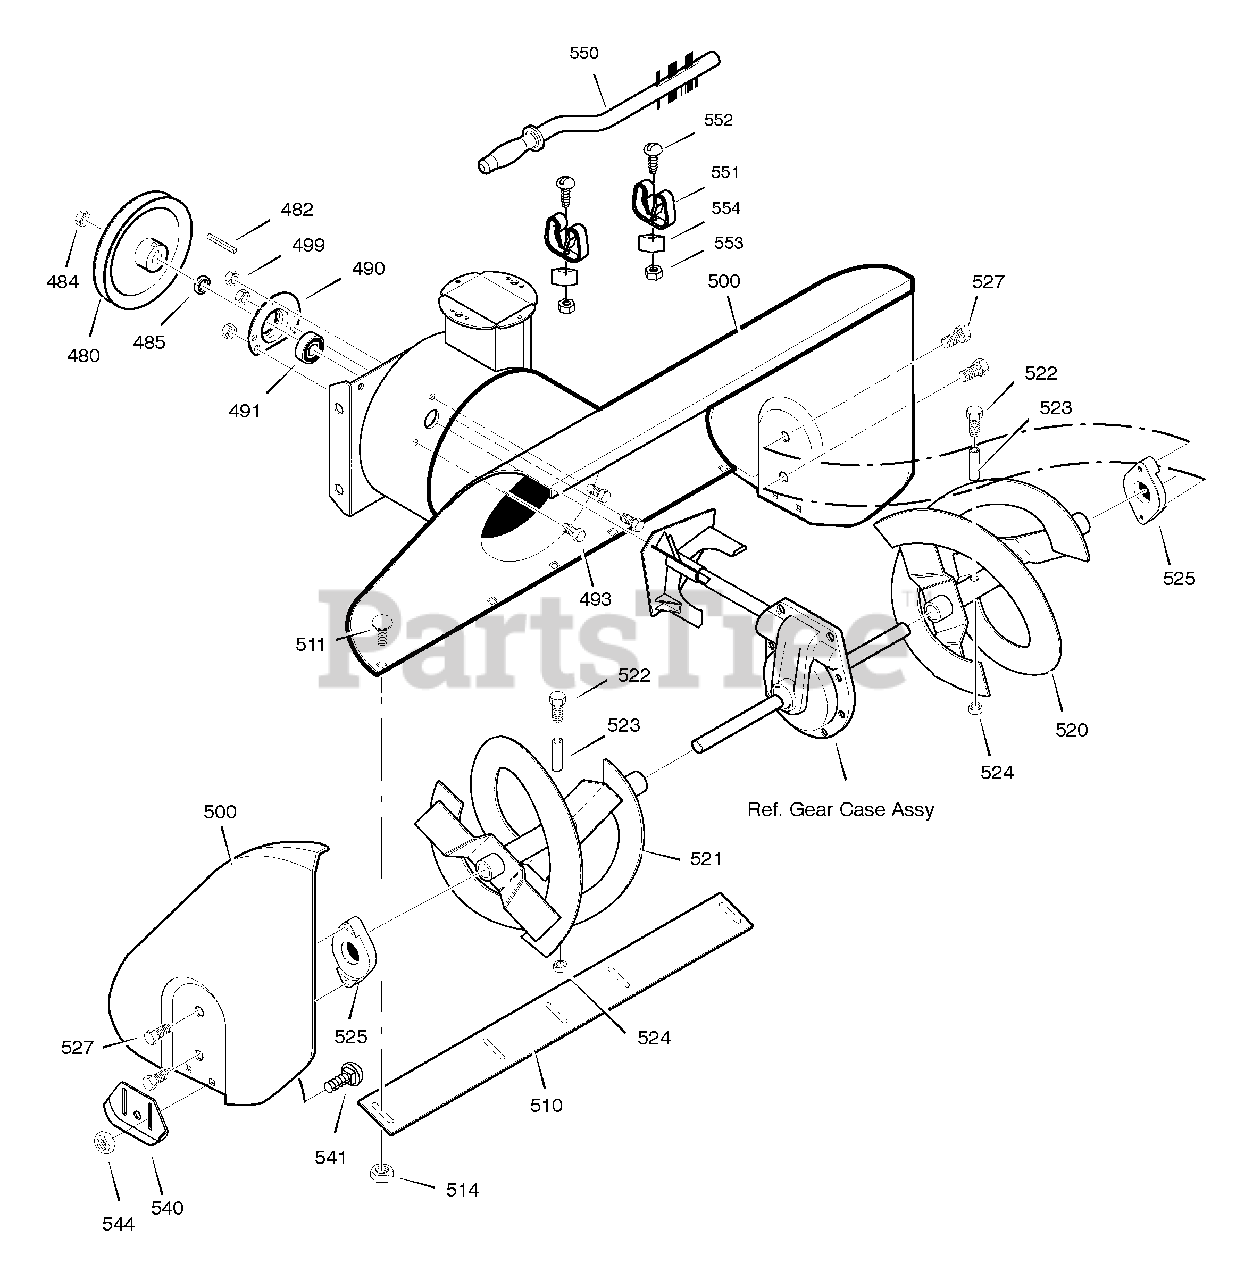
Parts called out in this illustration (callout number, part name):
480	PULLEY, 4L 8.40 OD
482	KEY, SQUARE 3/16 X 3/4
484	NUT, 1/2-20
485	SPACER, FRICTION PULLEY
490	RETAINER, BALL BRNG
491	BEARING, BALL
493	BOLT, HEX 5/16-18x0.62
499	NUT, 5/16-18 HEXWDFLLK
500	AUGER HOUSING ASSEMBLY
510	BLADE, SCRAPER
511	BOLT, 5/16-18X.62
514	NUT, 5/16-18
520	AUGER, ASSY, LH
521	AUGER, ASSY, RH
522	SCREW, 1/4-20 X 1.75
523	SPACER, SLEEVE
524	NUT, 1/4-20
525	BEARING, FLANGE
527	SCREW, 5/16-18 x 0.75
540	SKID, HEIGHT ADJUST
541	BOLT, CARRIAGE 5/16-18x0.50
544	NUT, 5/16-18
550	BRUSH, CLEANOUT
551	CLIP, RETAINER
552	SCREW
553	NUT
